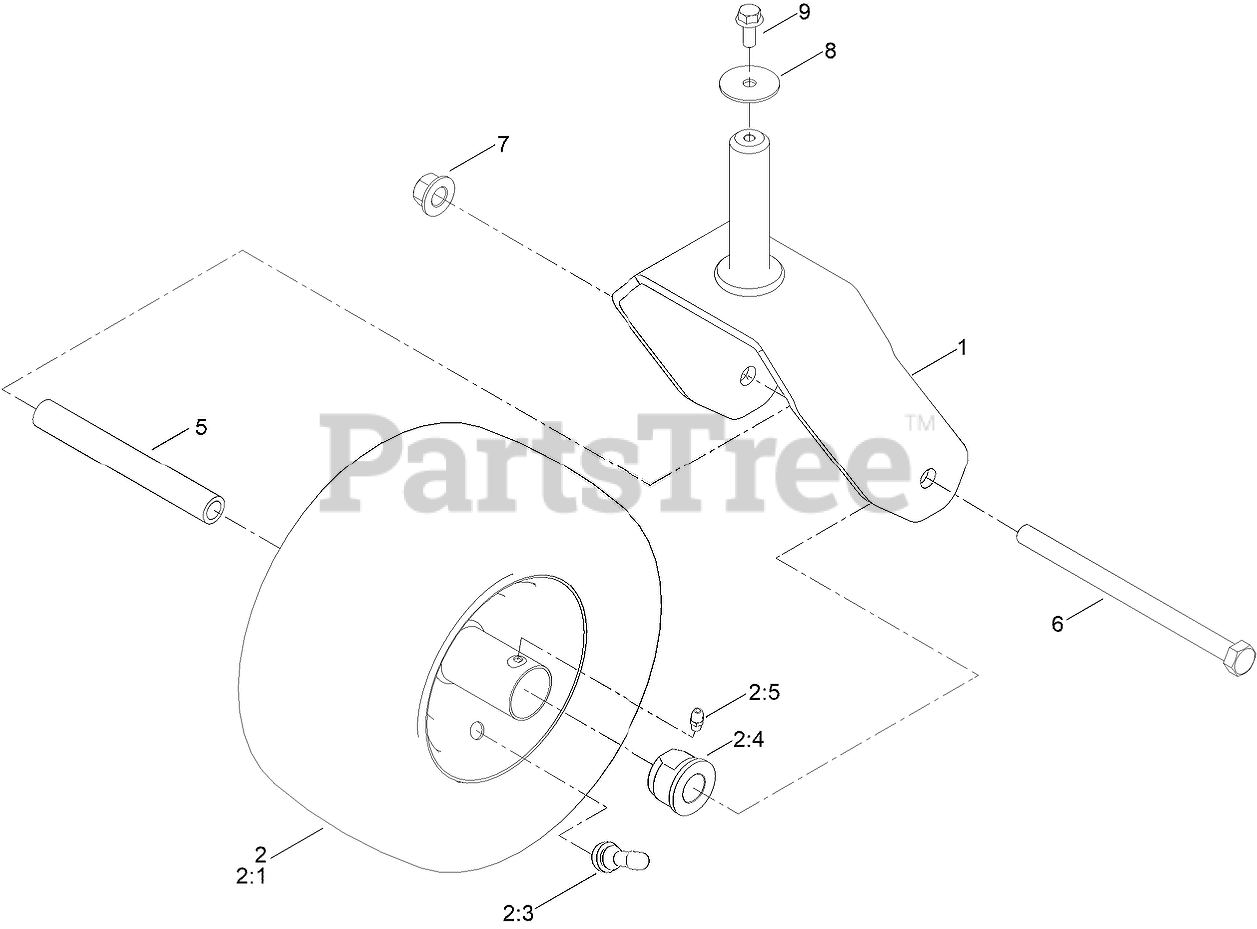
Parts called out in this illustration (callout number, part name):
1	FORK ASM
2	TIRE ASM
2:4	BUSHING-FLANGE
2:5	FITTING-GREASE
5	SPACER-SPANNER
6	SCREW-HH
7	NUT-LOCK
8	WASHER-FLAT
9	SCREW-HHF
